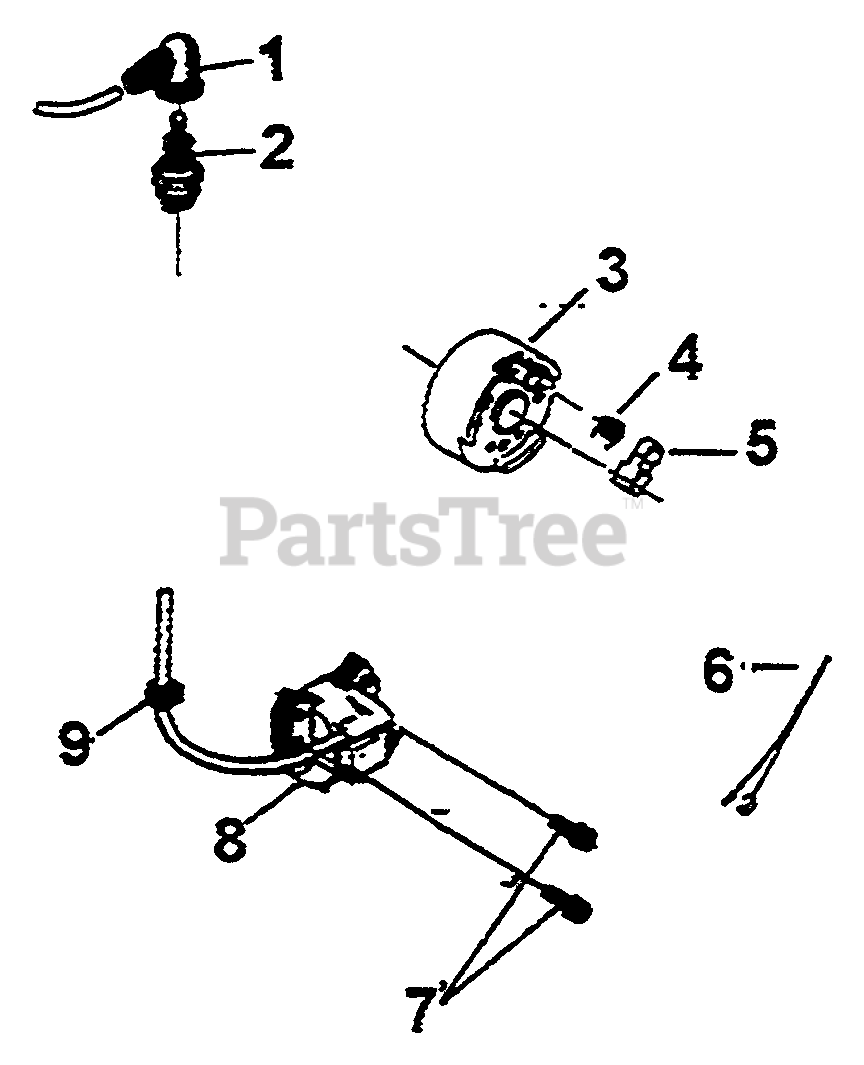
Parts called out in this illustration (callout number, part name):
1	CAP, PLUG
2	SPARK PLUG
6	HARNESS, WIRE
7	BOLT & WASHER
8	COIL, IGNITION
